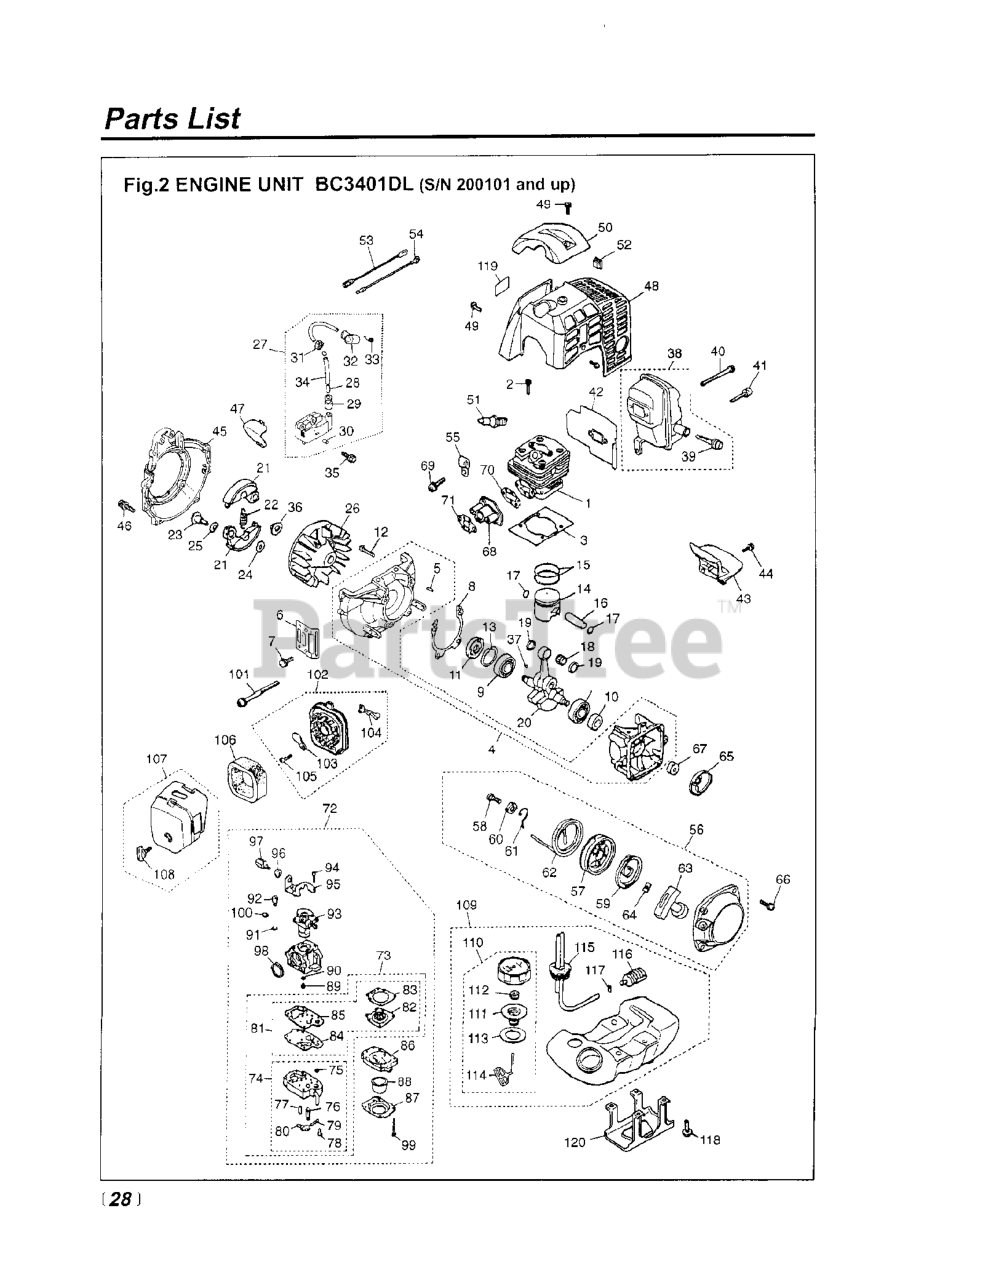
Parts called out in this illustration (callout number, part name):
1	CYLINDER
4	CRANKCASE
5	PIN
15	RP_RING.PISTON
16	PIN
18	ROLLER BEARING
19	WASHER
20	CRANKSHAFT COMPL
24	WASHER
26	ROTOR
27	COIL-A
28	CORD.HIGH
29	RedMax TBD
30	PIN
31	GROMMET
34	TUBE (RPLS 263072210)
36	NUT
37	KEY
38	MUFFLER ASSEMBLY
39	ARRESTER
40	BOLT, M5 x 60
42	GASKET
43	PLATE.MUFFLER
45	COVER
48	COVER.ENGINE
53	CORD
54	CORD
56	RECOIL ASSY
59	SPRING, SPIRAL
60	COLLAR
61	SWING ARM
68	INSULATOR
74	CARBURETOR BODY
87	1OVER
91	RING
92	SWIVEL
94	SCREW
95	BRACKET
96	NUT
98	RING PACKING
100	WASHER
102	BODY ASSY.
103	PLATE, CHOKE
104	LEVER.CHOKE
105	SCREW
107	COVER-A
109	TANK-A
110	CAP A
111	HOLDER-A
115	PIPE COMPLETE
116	FILTER ASSY
117	CLIP
119	LABEL
120	TANK GUARD
